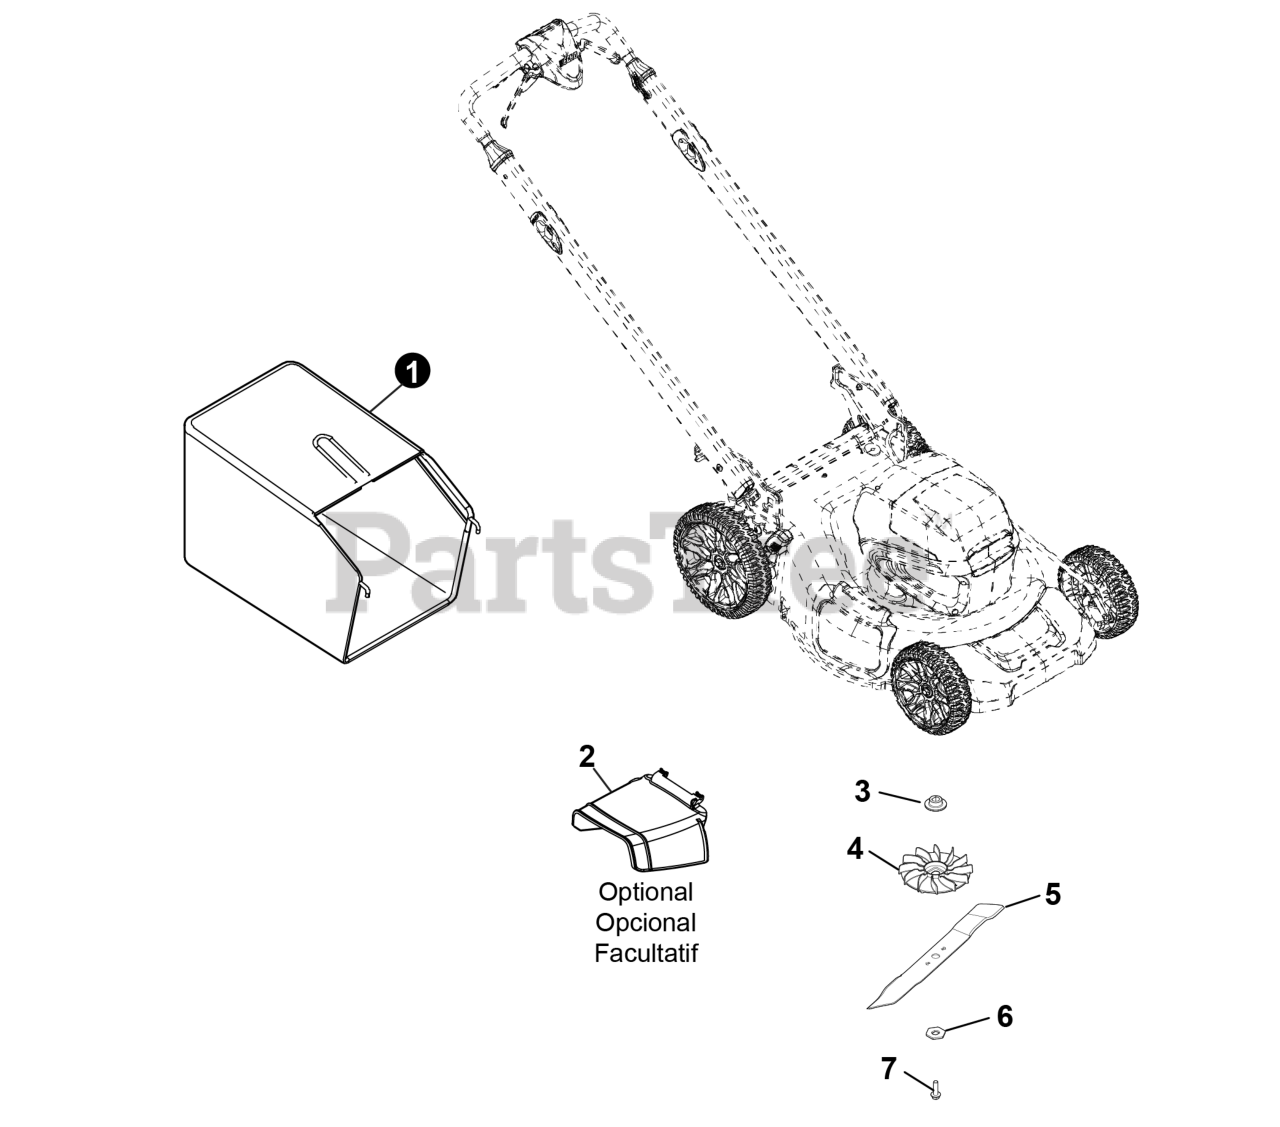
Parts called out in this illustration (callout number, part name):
1	BAG ASSY, GRASS
2	CHUTE, SIDE DISCHARGE
3	ADAPTER,BLADE
7	BOLT, BLADE
